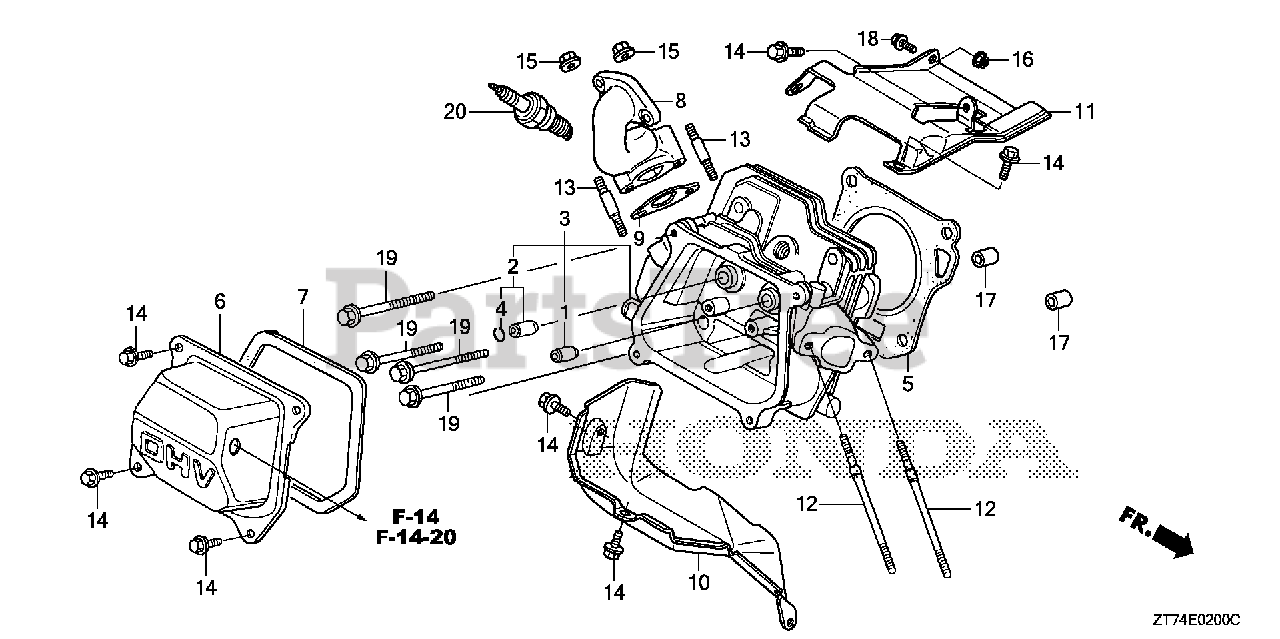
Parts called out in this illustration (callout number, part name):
1	GUIDE, VALVE (OVER SIZE) Use from Engine SN 6324986.
2	GUIDE, EX. VALVE (OS)
3	CYLINDER HEAD
4	CLIP, VALVE GUIDE Use from Engine SN 1231803.
5	GASKET, CYLINDER HEAD (NIPPON LEAKLESS)
6	COVER, HEAD
7	GASKET, CYLINDER HEAD COVER
9	GASKET, MUFFLER
10	SHROUD
11	SHROUD (UPPER)
12	BOLT, STUD (6X109)
13	BOLT, STUD (8X65) (CT200)
14	BOLT, FLANGE (6X12) (CT200)
15	NUT, FLANGE (8MM)
16	NUT, FLANGE (6MM)
17	PIN A, DOWEL (10X16)
18	BOLT, FLANGE (6X18)
19	BOLT, FLANGE (8X60)
20	SPARK PLUG (BPR5ES) (NGK)
20	SPARK PLUG (W16EPR-U) (DENSO)
20	SPARK PLUG (BPR6ES) (NGK)
20	SPARK PLUG (W20EPR-U) (DENSO)
